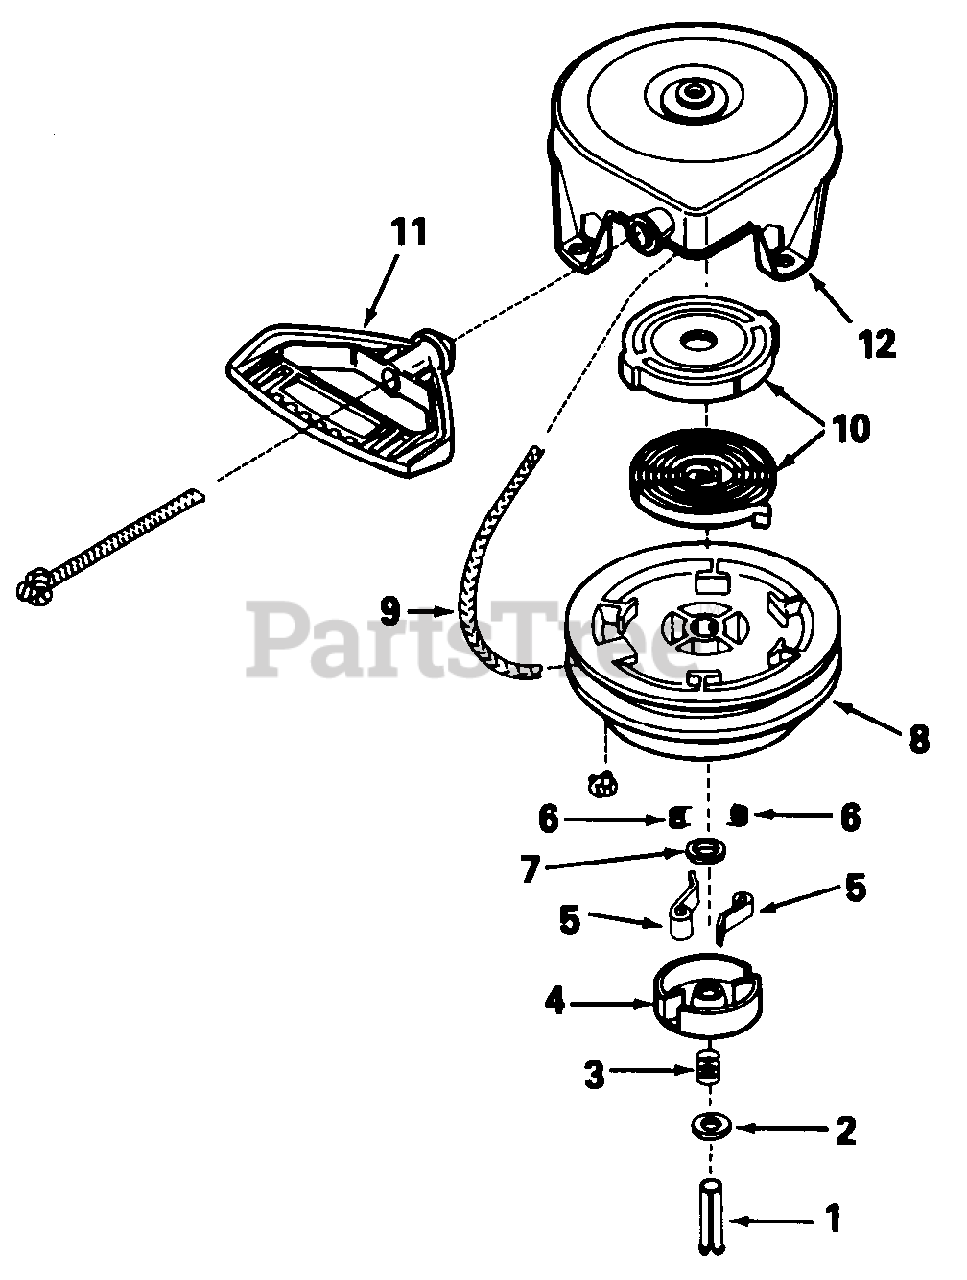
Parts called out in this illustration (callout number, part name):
1	Pin, Spring
3	Spring, Brake
5	Dog, Starter
6	Spring, Dog
9	Rope, Starter
10	Spring & Keeper Ass'y.
11	Handle, Mitten Grip (Not Included With Starter)
12	Housing Ass'y., Starter
